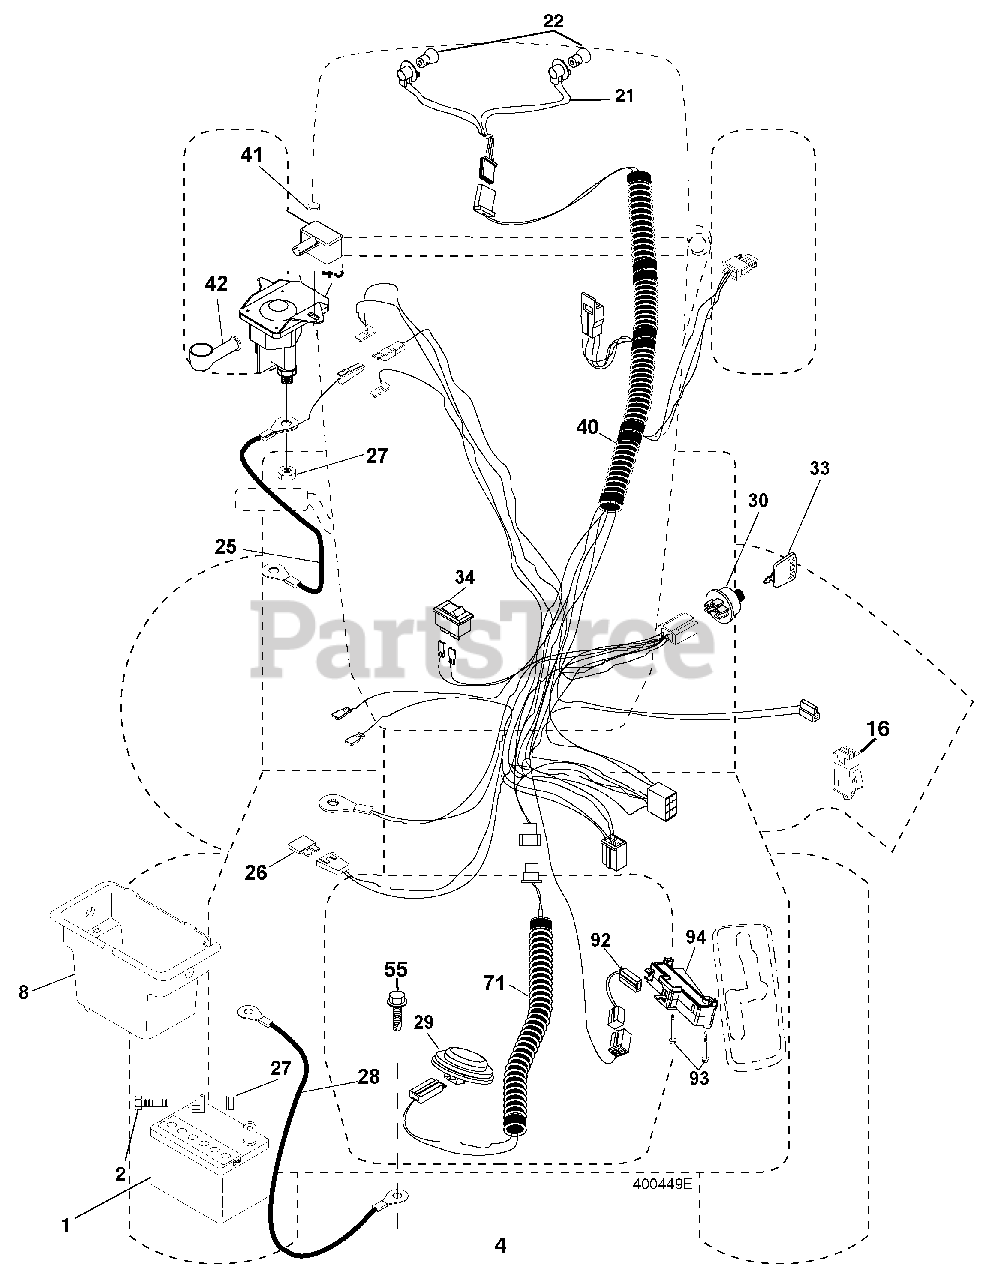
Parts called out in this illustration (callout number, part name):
1	Battery
2	Bolt Hex Hd 1/4-20 unc x 3/4
8	Box Battery
16	Switch Interlock
21	Harness Socket Light
22	Bulb, Light # 1156
25	Cable Battery 6 Ga. Red 14.5
26	Fuse
27	Nut Keps Hex 1/4-20 unc
28	Cable Ground 18" Rear Battery Blk 6 Ga.
29	Switch Seat
30	Switch Ign
33	Key Ign Molded Generic
34	Switch Light/Reset
40	Harness Ign
41	Screw 1/4-20 unc x 1/2
42	Cover Terminal Red
43	Solenoid
55	Screw 5/16-18 x 3/4
71	Harness Ign. Chass.
90	Cover Terminal
92	Harness Pigtail Reverse Switch
93	Screw Plastic 10-14 x 2.0
94	Modual Reverse ROS
